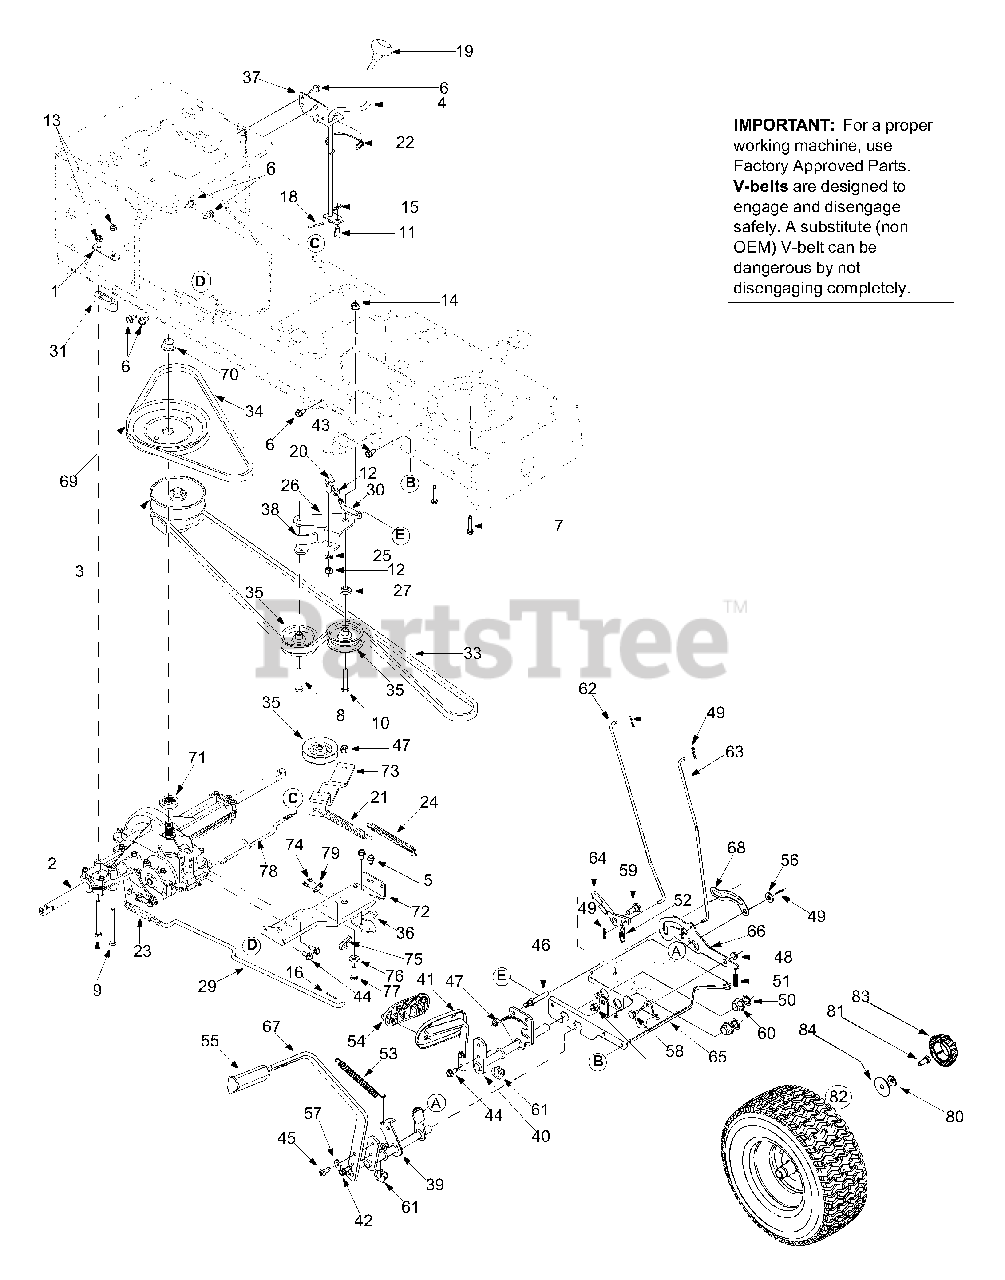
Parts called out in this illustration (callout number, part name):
2	Drive Assembly
3	Variable Spd. Pulley Assembly
4	Shift Lever Assembly
5	TT Screw 5/16-18 x 0.5
6	AB Screw 5/16-12 x 0.75
7	TT Screw 1/4-20 x 1.25
8	TT Sems Screw 3/8-16 x 1.5
9	Hex Bolt 5/16-18 x 3.5
10	Hex Bolt 3/8-16 x 2.0
11	Ferrule
12	Hex Nut 3/8-24
13	Hex Lock Nut 5/16-18
14	Flange Lock Nut 3/8-16
15	Hairpin Clip
16	Cotter Pin
17	Hairpin Clip
18	Cotter Pin
19	Shift Knob
20	Ball Joint
21	Extension Spring
22	Spring Clip
23	Extension Spring
24	Extension Spring
25	Lock Washer 3/8
26	Grease
27	Shoulder Spacer
28	Shift Rod
29	Brake Rod
30	Idler Adj. Rod
31	Spacer: Transaxle
32	Spacer
33	V Belt
34	V Belt
35	Flat Idler Pulley
36	Shift Bracket
37	Shift Bracket
39	Brake Control Assembly
42	TT Screw 5/16-18 x 0.875
43	AB Screw 5/16-12 x 0.75
44	LD Screw 5/16-18 x 0.75
45	TT Screw 5/16-18 x 0.75
46	Pin
47	Hex Lock Nut 3/8-16
48	Flange Lock Nut
49	Cotter Pin
50	Push Nut
51	Compression Spring
52	Extension Spring (Models w/ cruise)
53	Extension Spring
54	Control Pad
55	Brake Pad
56	Flat Washer
57	Flat Washer
58	Shoulder Screw
59	Shoulder Screw (Models w/ cruise)
60	Hex Flange Bearing
61	Hex Flange Bearing: Split
62	Brake Lock Rod
63	Cruise Control Rod (Models w/ cruise)
64	Cruise Latch (Models w/ cruise)
66	Lock-Out Bracket
69	Transmission Pulley
70	Flange Nut 9/16-18
71	Pulley Hub
72	Transmission Torque Bracket
73	Idler Bracket
74	AB Screw #8-18 x 0.5
75	Spring Switch
76	Shoulder Spacer
77	Hex Bolt 3/8-16 x 1.0
78	Shift Rod
79	Insulator Nut Plate
80	Bell Washer
81	Hex Cap Screw
83	Hub Cap
84	Flat Washer
